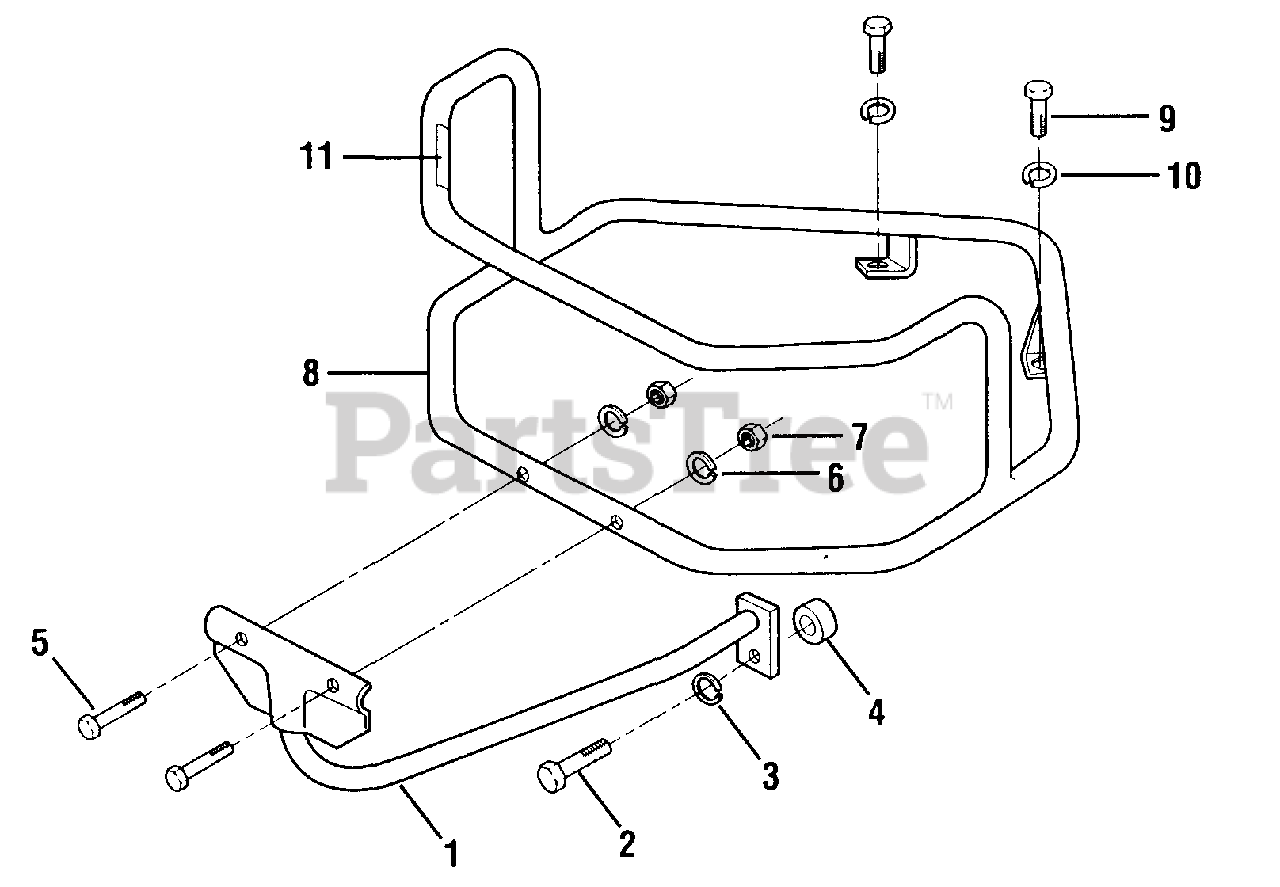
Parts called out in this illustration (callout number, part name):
1	Brace - bumper bottom
2	Bolt - hex hd., 1/2-13 x 1-1/2"
3	Lockwasher - spring lock, 1/2"
4	Spacer, 1/2"
5	Bolt - hex hd., 5/16-18 x 1-1/2"
6	Lockwasher - spring lock, 5/16"
7	Nut - hex, 5/16" 18
8	Bumper wraparound
9	Bolt - hex hd., 3/8-16 x 1"
10	Lockwasher - spring lock, 3/8"
11	Decal - for bumper
